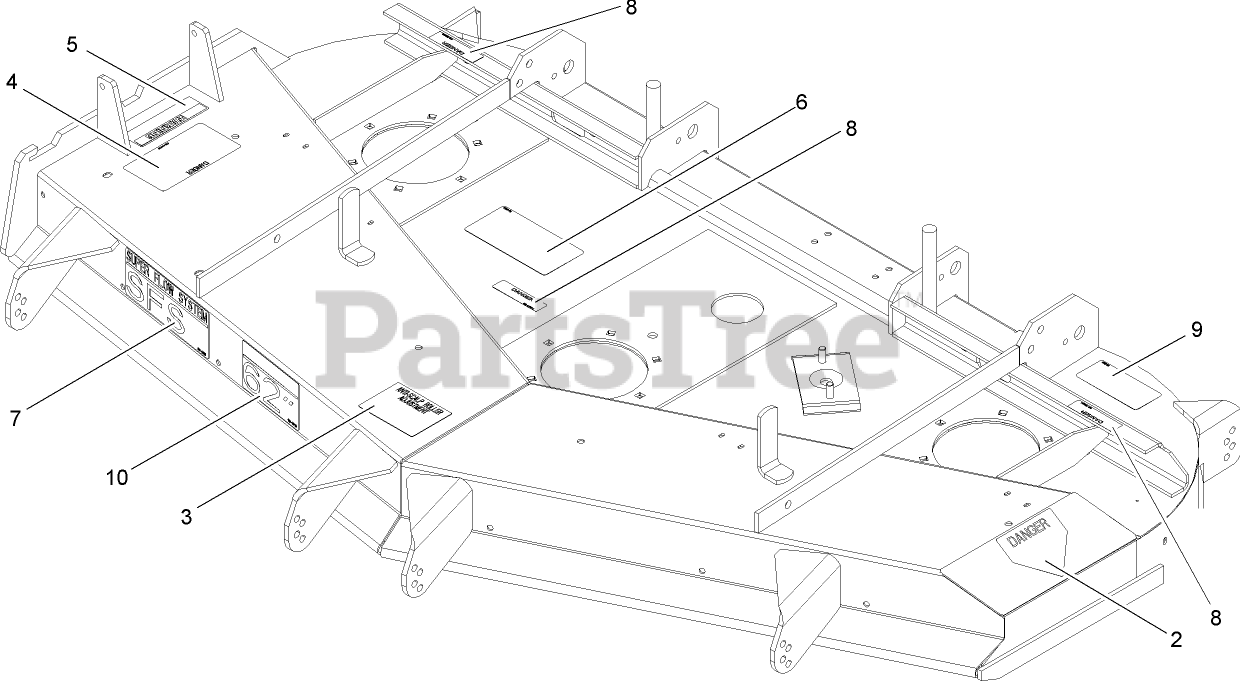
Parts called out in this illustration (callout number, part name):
2	DECAL-DANGER
3	DECAL-WHEEL, GAGE
4	DECAL-DANGER, THROWN OBJECT
5	DECAL-WARNING
6	DECAL-ROUTING, BELT
7	DECAL-SFS
8	DECAL-COVER, MISSING
9	DECAL-TORQUE, BLADE BOLT
10	DECAL-DECK
